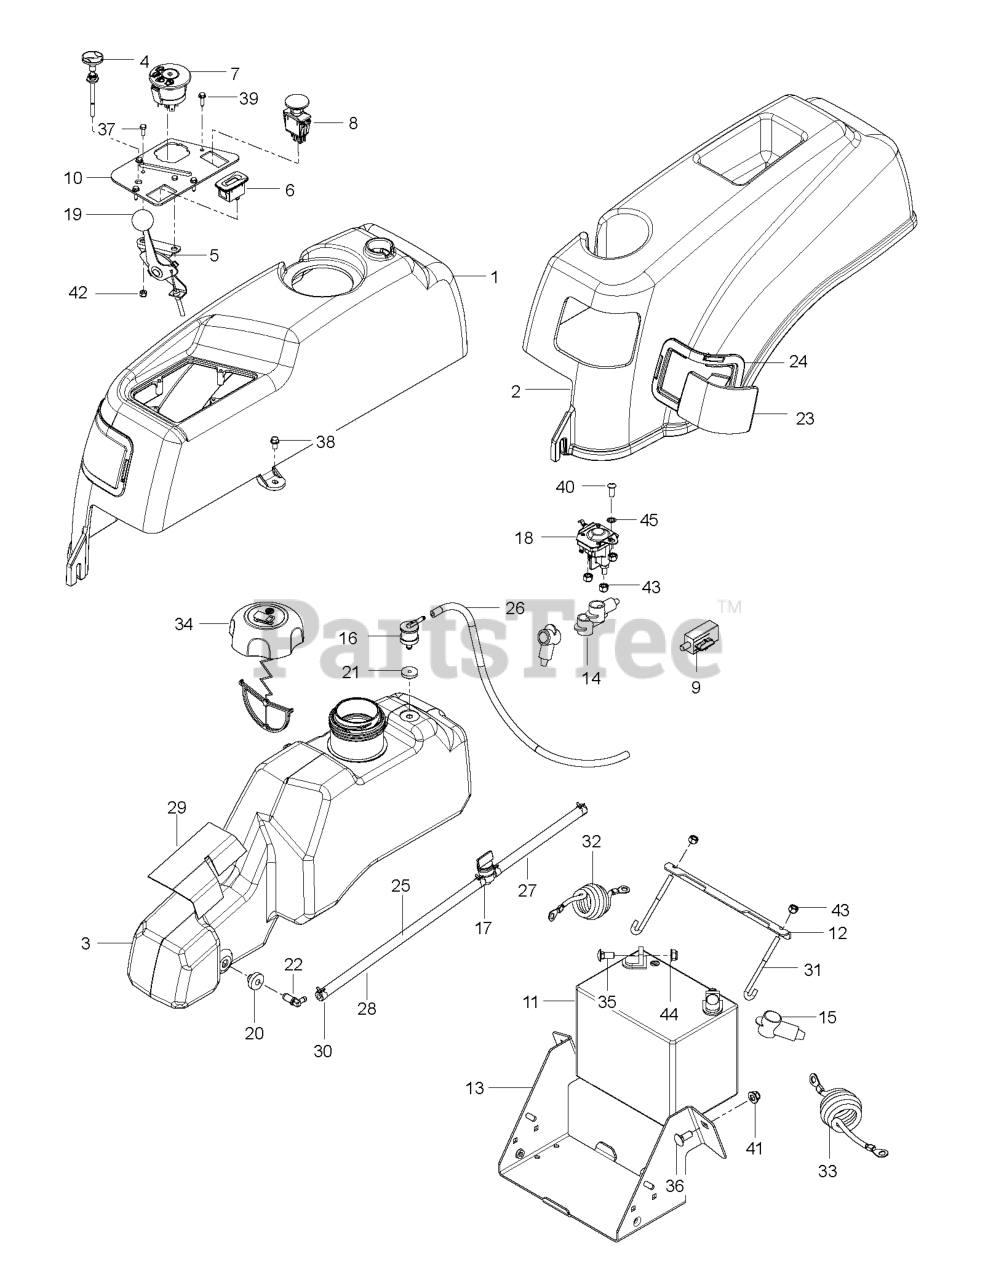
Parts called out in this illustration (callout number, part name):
1	FENDER.RT.BLK.3IN.FUEL.NECK
2	FENDER, LT, BLK
3	FUEL TANK ASSY LARGE 3 NECK TH
4	CHOKE CABLE
5	THROTTLE CABLE
6	GUAGE.SRVCMNDR.HRMTR.
7	RP IGNITION SWITCH
8	RP SWITCH.PTO.TERMINAL.STD.RED
9	SWITCH.INTRLCK.CLUTCH.
10	CONTROL PLATE RZ STD X431
11	BATTERY, 12 V 330 AMP
12	BRACKET.PNT.MOUNT.BATTERY.EDIP
13	BOX.PNT.BATTERY.RZ.EDIP
14	TERMINAL COVER
15	INSULATOR
16	VALVE.FUEL.CHECK
17	FUEL VALVE
18	SOLENOID.STARTER.BRASS.PLUNGER
19	KNOB.ROUND.BALL.BLACK
20	BUSHING OUTLET T
21	GROMMET, CHECK VALVE
22	STEM FUEL TANK
23	PANEL, LT
24	RING, TRIM LT BLK
25	FUEL.HOSE.SHUT.OFF.ASM.10".3"
26	HOSE 3/16" VAPOR LINE 44" LENG
27	HOSE.1/4".LOW.PERM.FUEL.LN.10"
28	HOSE 1/4" LOW PERMEATION FUEL
29	SHIELD, HEAT
30	HOSE CLAMP
31	HOOK.J.BATTERY
32	CABLE BATTERY GROUND RZ
33	CABLE BATTERY POS RZ
34	CAP ASSY FUEL 3" BLACK
35	BOLT 5/16C X 3/4" CARRIAGE
36	PLATE NUT ZTR
36	RHSNB 3/8C X 1
37	HCS #10-24 X 1/2
38	SCREW
39	SCR #10-12X3/4 HEX WAS HD ZD
40	SCR 1/4-20 X 5/8 BTN SKT HD ZD
41	NUT 3/8-16 HEX FLG NYLOC ZD
42	NUT 10-24 NYLOC
43	RP_NUT 1/4-20 NYLOC
44	5/16-18 NYLOC FLANGE NUT
45	WASHER 1/4 INT TOOTH
